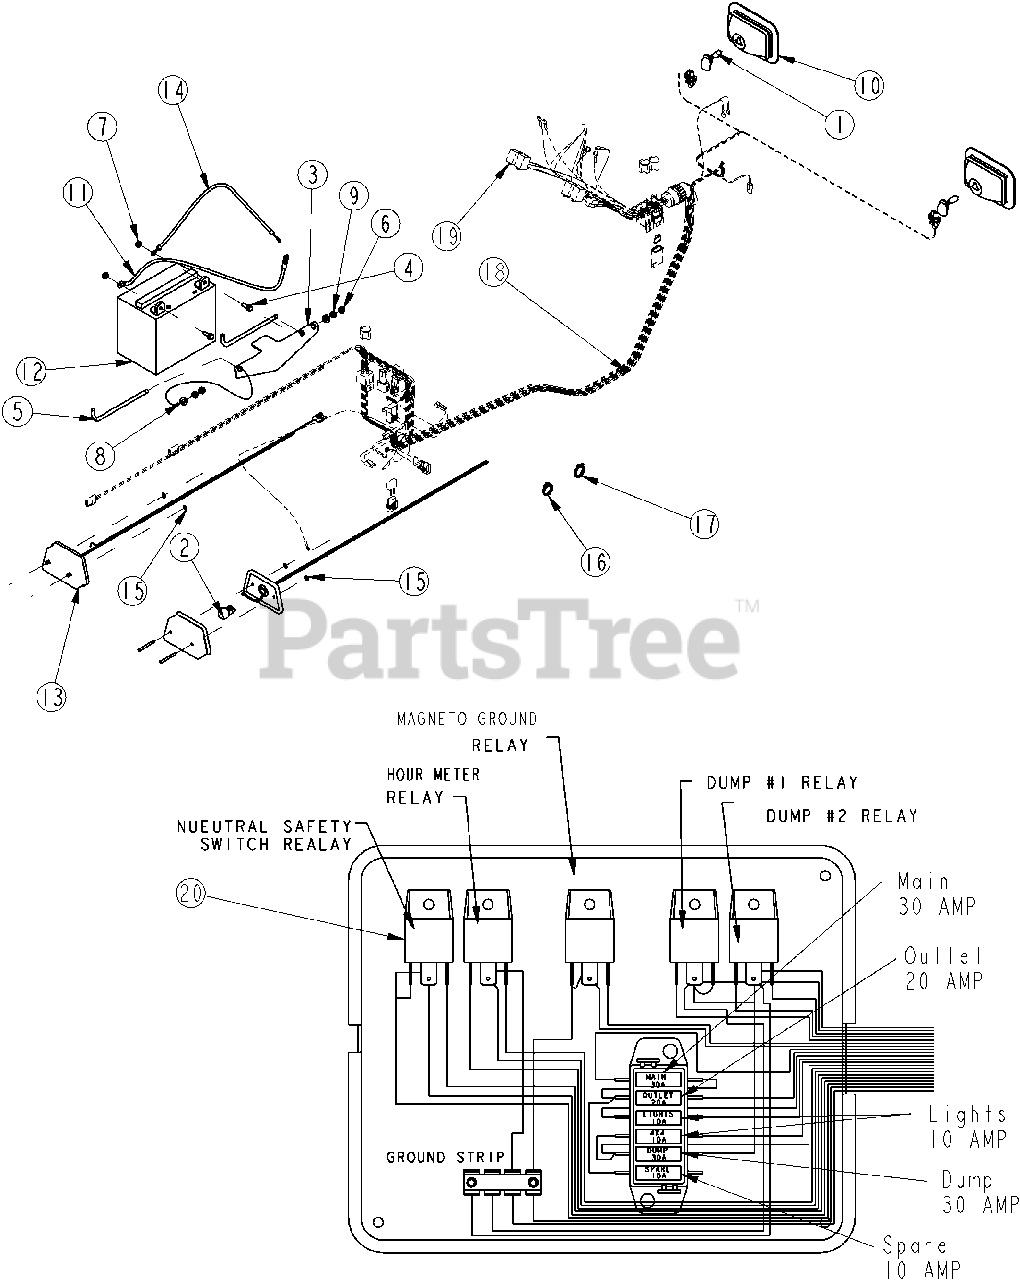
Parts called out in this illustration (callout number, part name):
1	HEADLIGHT BULB 37.5 WATT 894
2	TAILLIGHT BULB 1157 1157
3	HOLDOWN, BATTERY ST
4	HFSS 1/4-20X3/4 GR5
5	SP HOOK 5/16-18X9X3 THREAD
6	NUT, HEX 5/16-18 PLT
7	NUT HEX FLNG T-LOCK 1/4-20 YLW
8	WASHER, FLAT 5/16 SAE
9	WASHER, LOCK 5/16
10	HEADLIGHT W/TRAP LENS 37.5WATT
11	BATTERY CABLE POSITIVE 15 INCH
12	BATTERY BUY LOCALLY BCI Group U1/U1R, Min. 300CA
13	TAIL LIGHT WITH STANDARD LEAD
14	20" 6GA NEGATIVE BLACK CABLE
15	PUSH RETAINERS 4 NON-THRD SHFT
16	CABLE TIE .19X14.25 3DIA 50LB
17	CABLE TIE 2 DIA MIN - BLK
18	WIRING HARNESS, MAIN ST
19	WIRE HARNESS INSTRUMENT PANEL
20	-209-150 RELAY BOSCH
